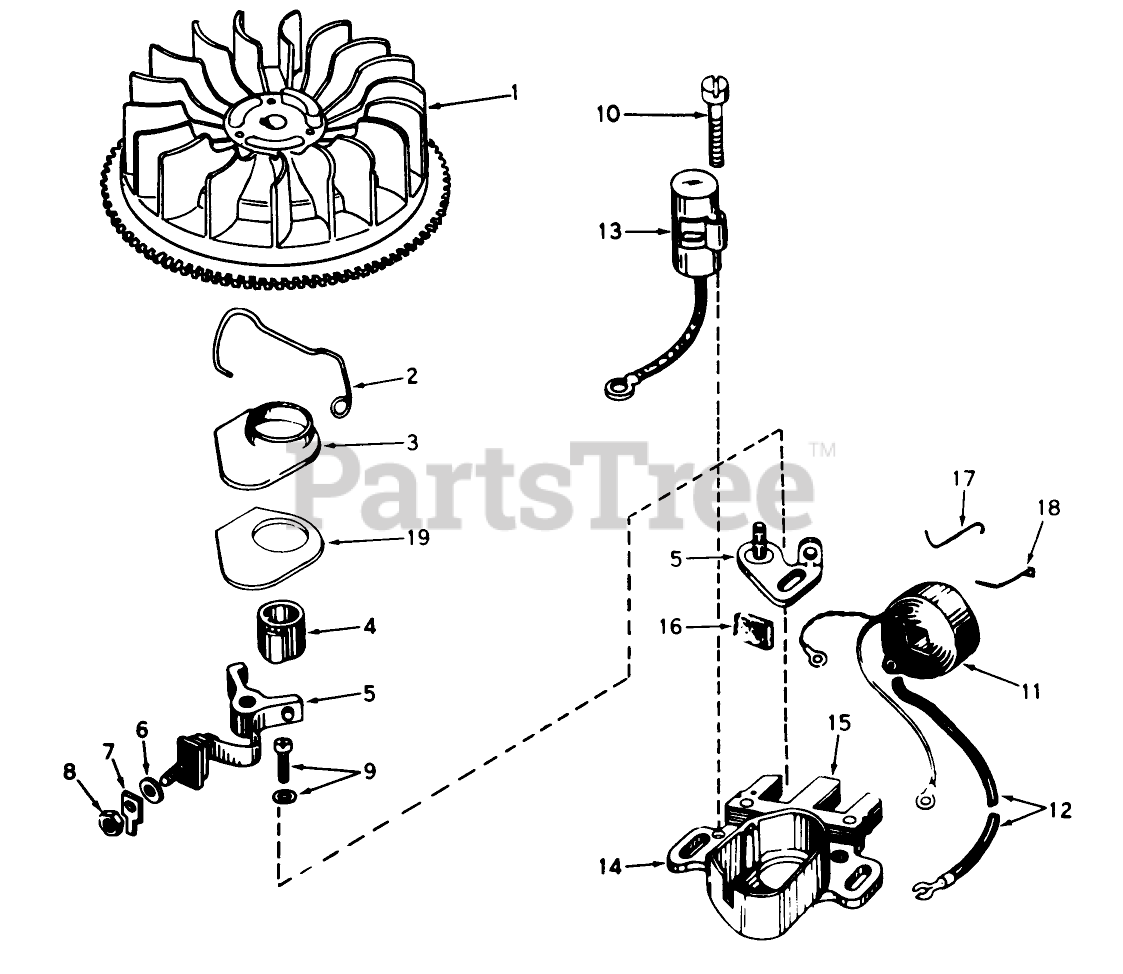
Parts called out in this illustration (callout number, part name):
1	FIywheel
2	Spring Breaker Box
3	Cover, Dust
4	Cam-Breaker
5	Breaker Assy.
6	Washer
7	Terminal
8	DECAL
9	Breaker Screw
10	Condenser Screw
11	Coil Assy. (Incl. No. 12)
12	Wire, Lead
13	Condenser
14	Core Plate
15	Stator Assy., (Incl. Nos. 2, 3, 5 thru 14 16 thru 19)
16	Felt,Cam Wiper
17	Clip, Coil
18	Spring Coil Wedge
19	Gasket Dust Cover
